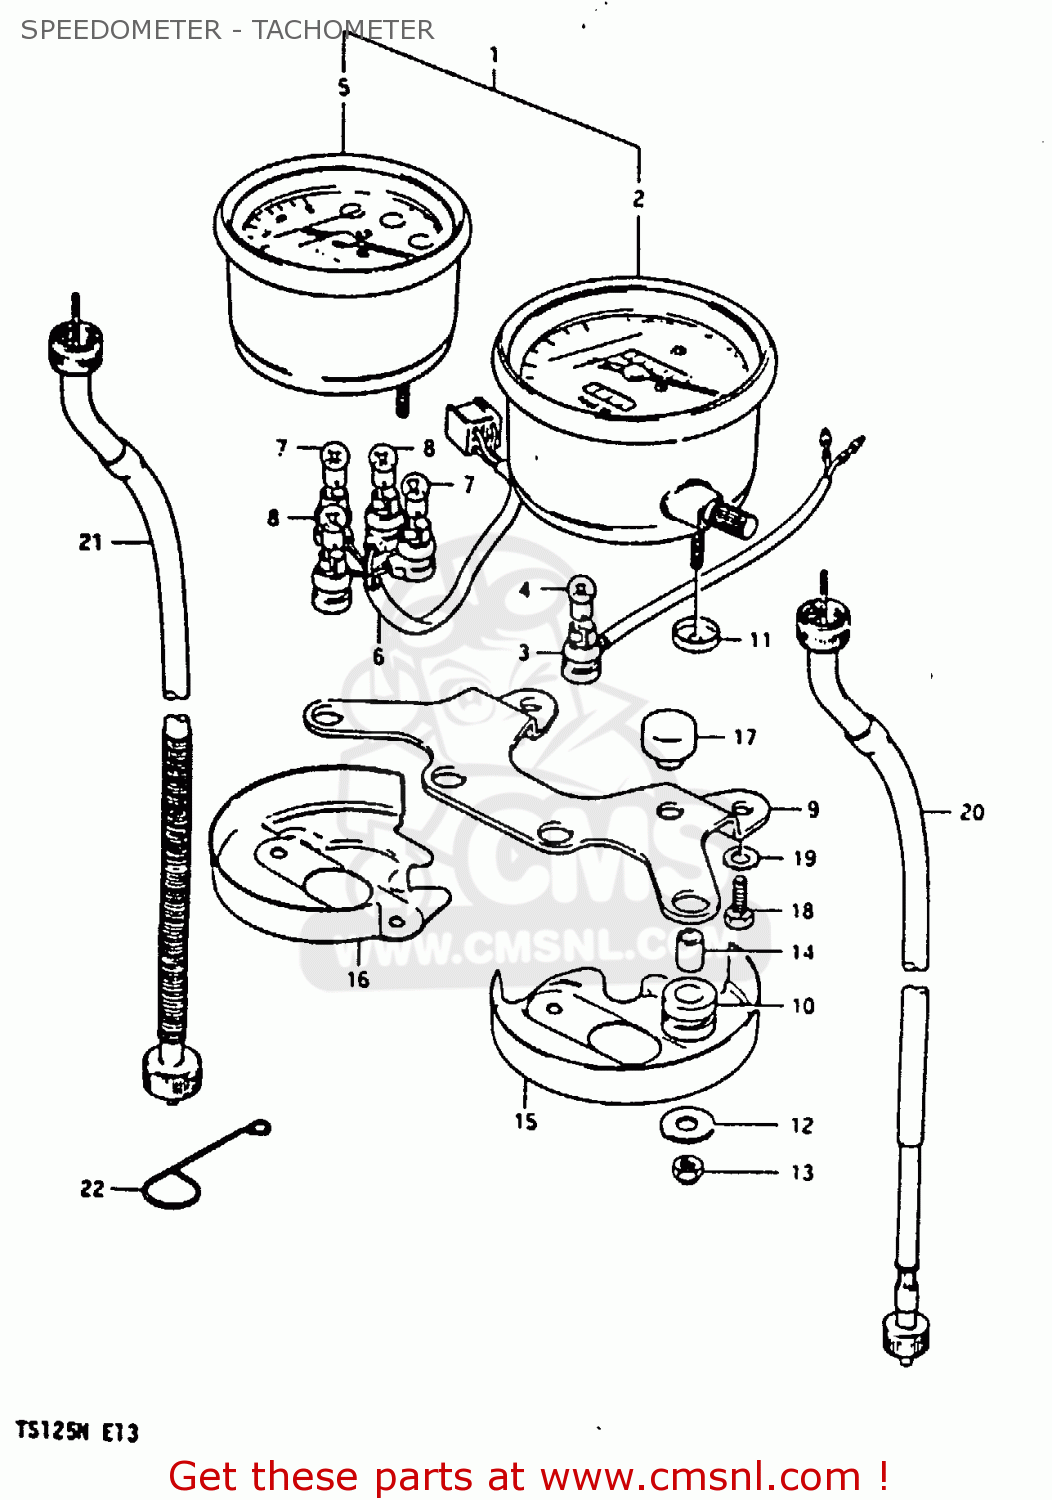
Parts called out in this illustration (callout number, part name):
1	METER ASSEMBLY,SPEEDOMETER/TACHOMETER
2	METER,SPEEDOMETER
3	SOCKET,SPEEDOMETER
4	BULB(6V1.7W,STANLEY,A61A)
5-	METER,TACHOMETER
6	SOCKET,TACHOMETER
7	BULB(6V1.7W,STANLEY,A61A)
8	BULB(6V/3W)
9	BRACKET,COMBINATION METER
10	CUSHION,METER
11	WASHER
12	WASHER,METER
13	NUT
14	SPACER,SPEEDOMETER
15	COVER
16	PLATE,TACHOMETER UNDER
17	CUSHION,METER
18	BOLT, UPPER
19	WASHER
20	CABLE, SPEEDOMETER
21	CABLE ASSEMBLY,TACHOMETER
22	GUIDE,TACHOMETER CABLE
